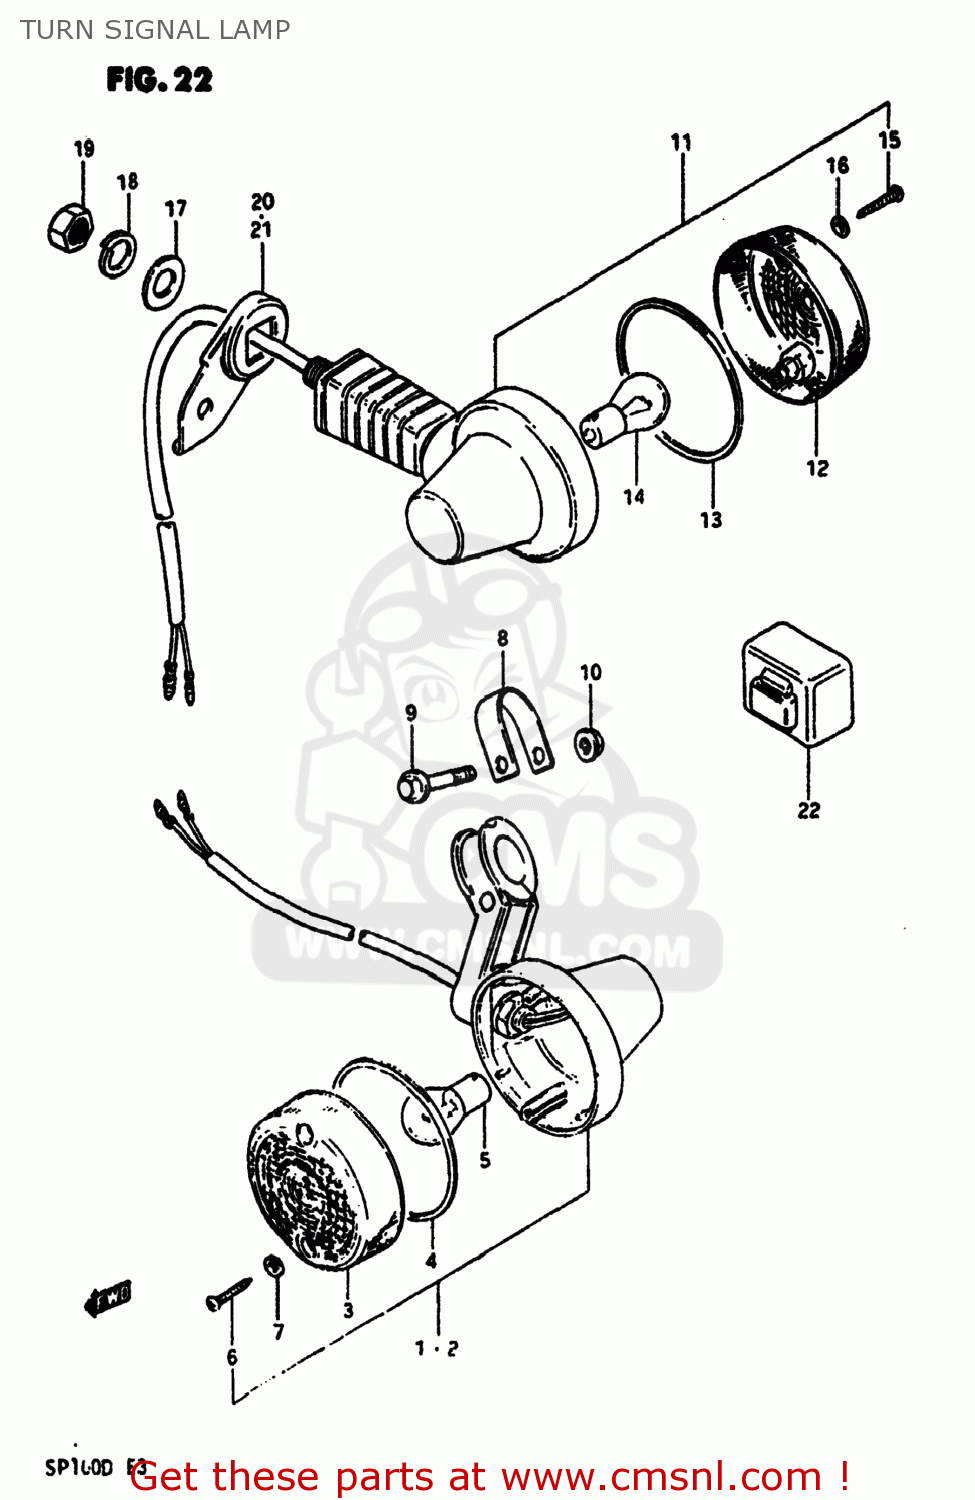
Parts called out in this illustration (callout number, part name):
1	LAMP ASSEMBLY,FRONT TURN SIGNAL
2	LAMP ASSEMBLY,FRONT TURN SIGNAL
3	LENS
4	GASKET (NAS)
5	BULB(6V17W,STANLEY,A4513A)
6	SCREW TAPP.
7	GASKET (NAS)
8	PLATE
9	BOLT 5X42
10	NUT
11	LAMP ASSEMBLY,REAR TURN SIGNAL
12	LENS
13	GASKET (NAS)
14	BULB(6V17W,STANLEY,A4513A)
15	SCREW TAPP.
16	GASKET (NAS)
17	WASHER
18	WASHER,LOCK 12
19	NUT
20	BRACKET,REAR TURN SIGNAL
21	BRACKET,REAR TURN SIGNAL
22	RELAY,TURN SIGNAL
